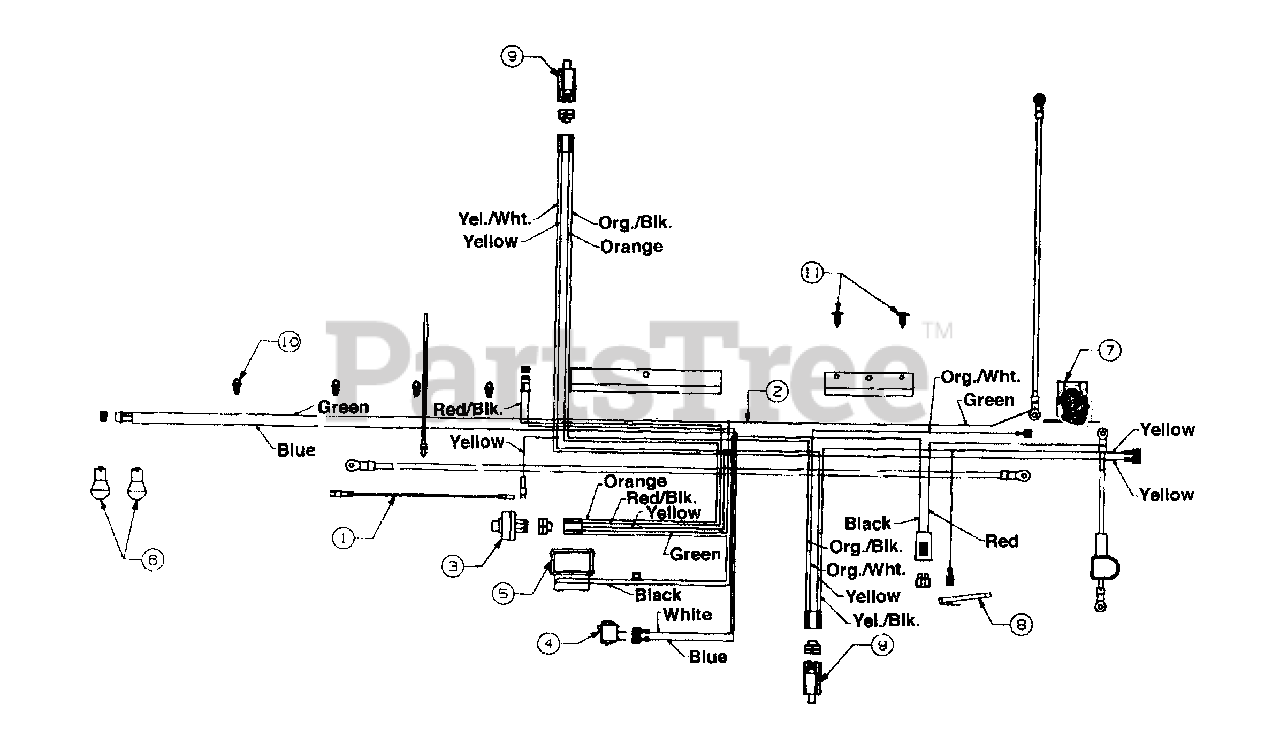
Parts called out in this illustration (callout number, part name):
1	Harness Adapter (Mag.)
2	Wire Harness w/Light Switch and Amp
3	Ignition Switch
4	Light Switch
5	Ammeter
6	Bulb (Headlight)
7	Solenoid
8	Safety Switch (Reverse)
9	Safety Switch
10	Wire Retainer Clip
11	Ratchet
